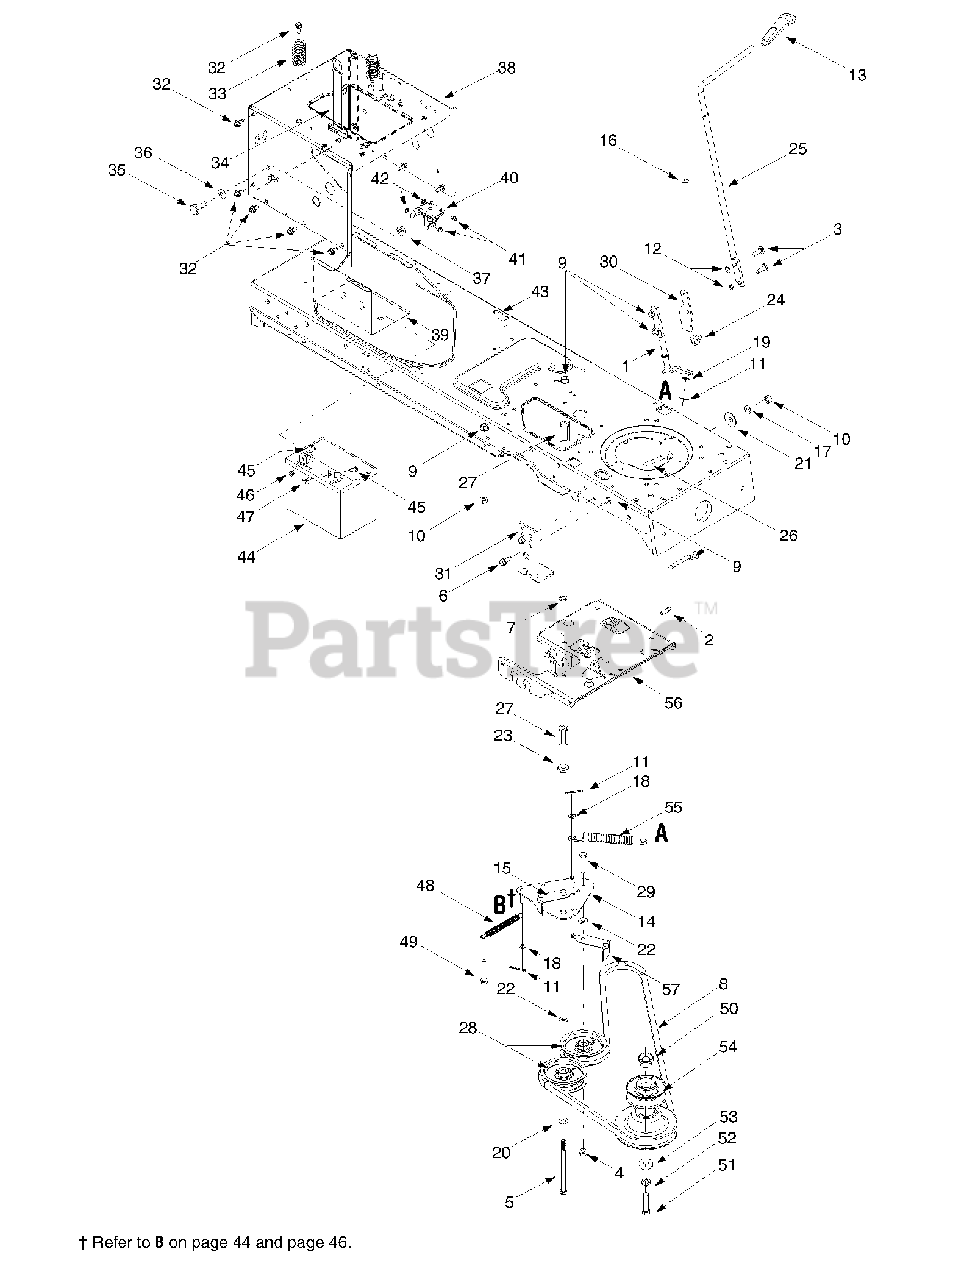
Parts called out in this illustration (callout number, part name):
1	PTO Engagement Lever Assembly
2	Belt Keeper Rod
3	Carriage Screw, 5/16-18 x 1.00
4	Flange Lock Nut, 3/8-16
5	Hex Cap Screw, 3/8-16 x 5.5
6	Hex Head Washer Screw, 5/16-18 x .875
7	Push Nut, 3/8
8	PTO Belt (Models w/ 46-inch deck)
9	Flange Lock Nut, 5/16-18
10	Hex Nut, 5/16-18
11	Cotter Pin, 1/8 x 1.25
12	Speed Nut, .3125
13	PTO Knob
14	PTO Engagement Plate Assembly
15	Belt Guard
16	Flat Washer, .510 x .750 x .033
17	Lock Washer, 5/16
18	Flat Washer, .385 x .62 x .063
19	Flat Washer, 5/16
20	Flat Washer, .406 x .875 x .059
21	Bell Washer, .39 x 1.13 x .062
22	Flat Washer, .407 x .812 x .135
23	Shoulder Spacer, .380
24	Hex Split Flange Bearing, .5
26	Belt Keeper Rod
27	Spacer, 3/8 x 1.54
28	Idler Pulley, 3.5
29	Hex Cap Screw, 3/8-16 x 1.75
32	Self Tapping Screw, 5/16-18 x .625
33	Compression Spring, 1.28 x 3.5
34	Battery Strap
35	Shoulder Screw, .625 x .5, 7/16-20
36	Bell Washer, .45 x 1.0 x .062
37	Flange Lock Nut, 7/16-20
41	Self Tapping Screw, 1/4-20 x .5
42	Lock Washer, 1/4
45	Hex Cap Screw, 1/4-20 x .62
46	Hex Sems Nut, 1/4-20
47	Wing Nut, 1/4-20
48	Extension Spring, .50 x 5.0
49	Hex Cap Screw, 5/16-18 x 1.75
50	Spacer Cup
51	Hex Head Cap Screw, 7/16-20 x 1.25
52	Lock Washer, 7/16
53	Flat Washer, .450 x 1.25
54	Engine Pulley, 3.56 OD x 5.56
55	Extension Spring, .75 x 6.75
57	Belt Guard
